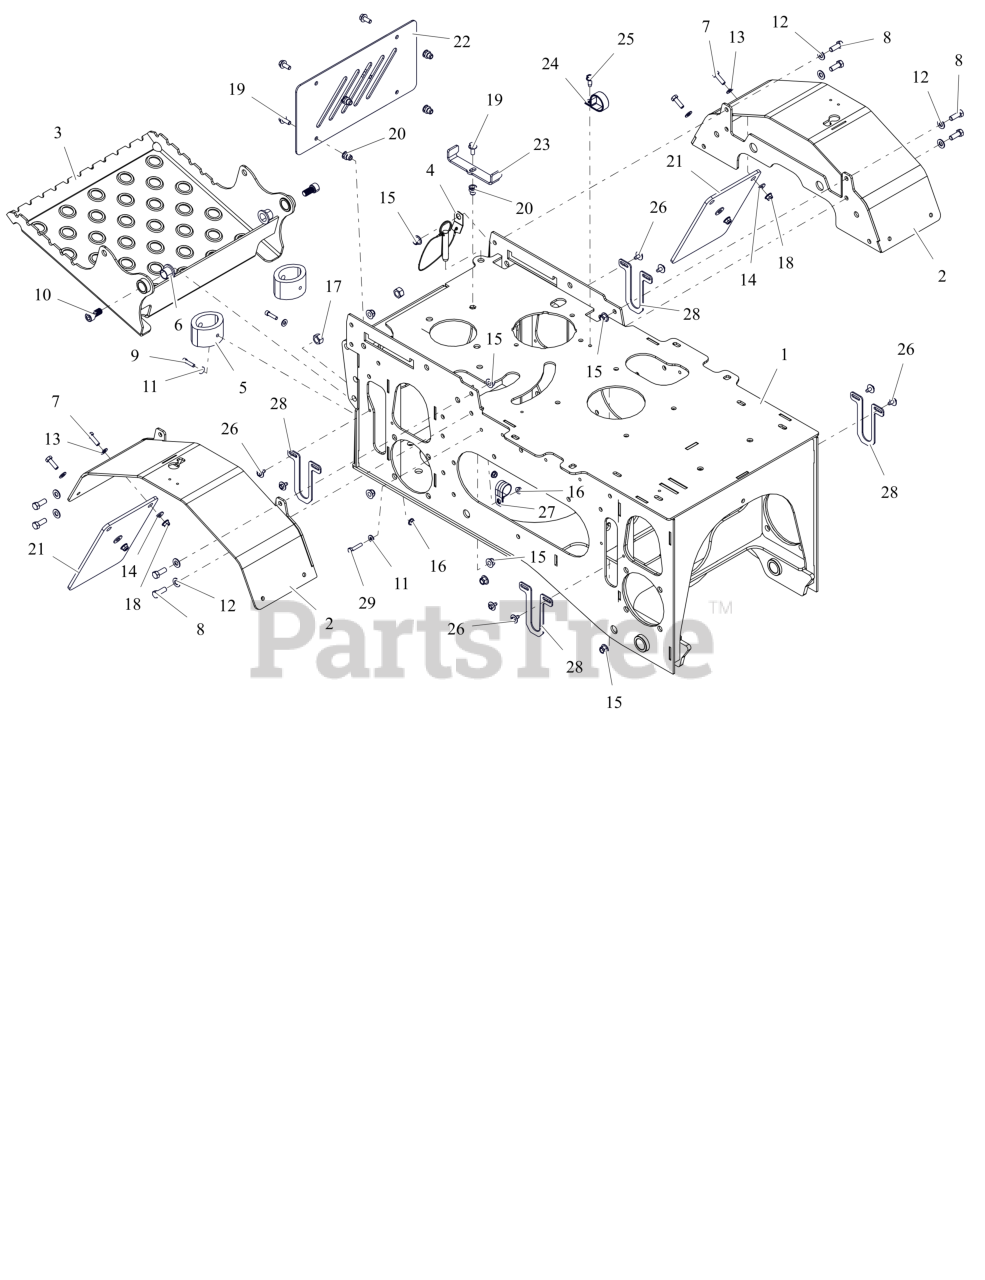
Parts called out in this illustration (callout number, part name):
1	WLDMT, FRAME
2	WLDMT- FENDER
3	WLDMT- OPERATOR PLATFORM
4	PIN, QUICK RELEASE,LANYARD,CLIP
5	BUMPER, PLATFORM
6	BSHG- FLANGE BRONZE
7	BLT,HEX .31-18X1.00 G5 ZCC
8	BLT,HEX .38-16X1.00 G5 ZCC
9	SCR, SKH .25-20X1.00
10	BOLT- SHCS 1/2-13 X 1.00"
11	WSHR,FLT .281X.625X.065 ZCC
12	WSHR,FLT .406X.812X.065 ZCC
13	WSHR,FLT .344X.688X.065 ZCC
14	WSHR,FLT .375X.875X.083 ZCC
15	NUT,NYL-FLG .38-16 GF ZCC
16	NUT-LK-CTR-FLG .25-20 ZC120
17	NUT,LK-CTR .50-13 GA ZCC
18	NUT,LK-NYL-FLG .31-18 G5ZC120
19	BLT- SERHFWH .312-18X.75 ZCC
20	RVT-NUT HEX 5/16-18 LONG
21	FLAP- FENDER - RUBBER
22	PANEL- ACCESS
23	PLATE- BATTERY TIE DOWN
24	CLAMP- CUSHIONED 1-3/8 X 11/32
25	SCR,TAP .312-18X.75 HWH TR ZCC
26	SCR, TAP .25-20X.50 LG HWH ZCC
27	CLIP- P-STYLE / 1.00 ID
28	PLATE, SPRG RETAINER
29	BLT, HEX .25-20X1.25 G5 ZCC
